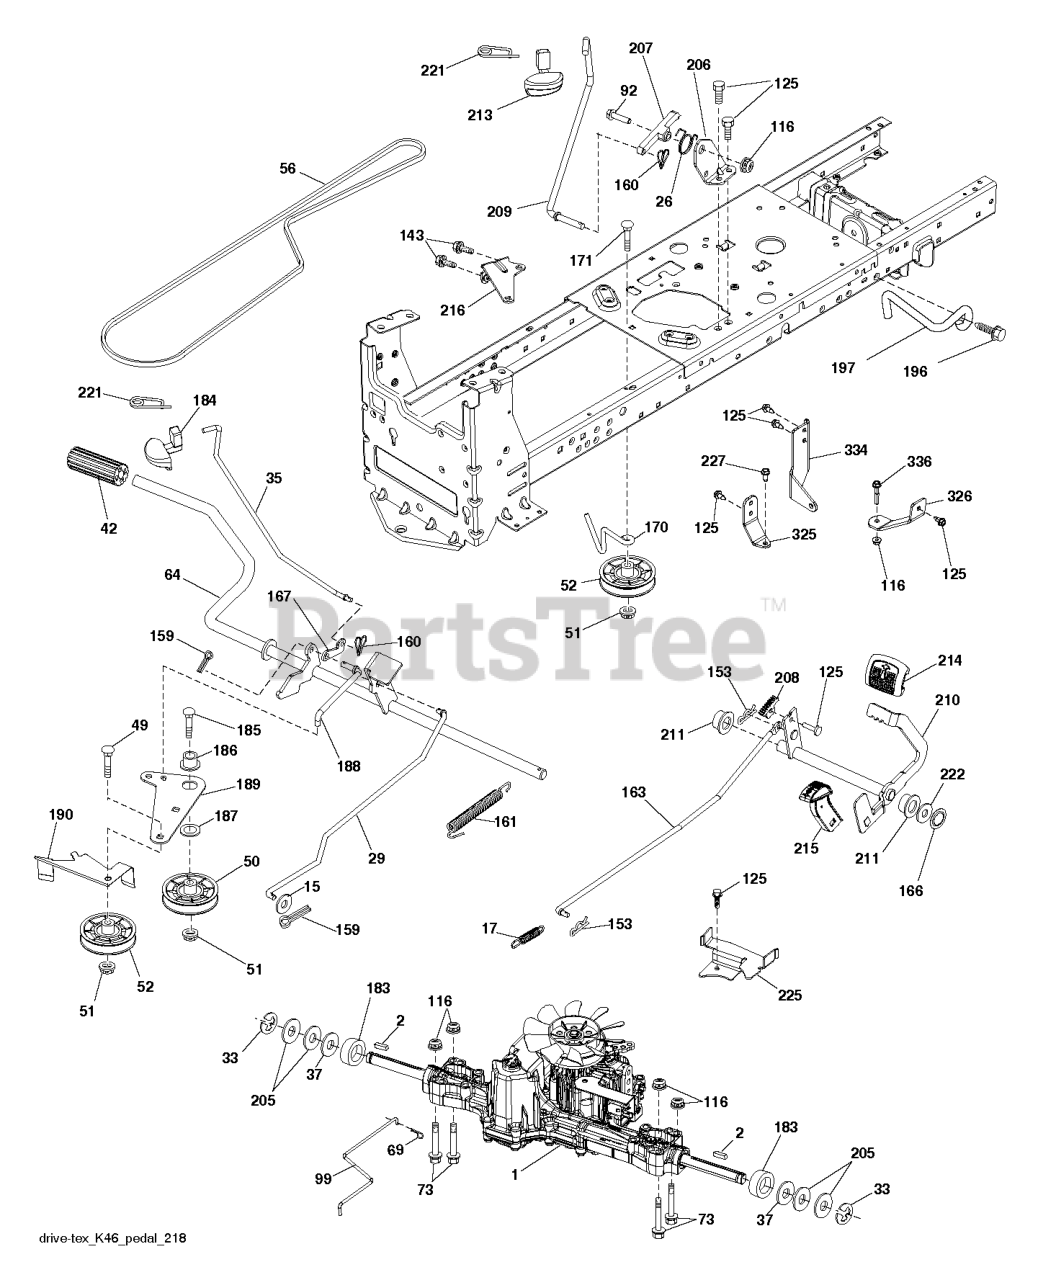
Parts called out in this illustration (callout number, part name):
2	SQUARE KEY
15	WASHER
17	SPRING.BRAKE.K46.GREEN
26	SPRING.RETURN.CRUISE
29	ROD.BRAKE.K46
35	ROD ROD.PARKINGBRAKE.GT.HUSQ/P
37	WASHER.HARDENED
42	PEDAL COVER T
50	IDLER.FLAT.910.OFFSET
51	NUT LOCK FLG 3/8-16 UNC
52	IDLER.V-GROOVE.910.OFFSET
56	V-BELT.MOWER.92.40.42/K46
64	SHAFT.ASM.PEDAL.BRK.CNTR
69	HAIRPIN.SOFT.ZINC.059X1.125
73	BOLT
92	BOLT
99	ARM.PIVOTING.TCRD.GEN2.5.BAGGE
116	NUT LOCK HEX FLANGE 5/16-18
125	SCREW
143	SCR 5/16-18 X 1/2 SELFTAP ZN
153	RETAINER M
159	COTTER PIN
160	RETAINER CLIP
161	SPRING, RETURN LT
163	ROD.CONTROL.K57R.K46
166	NUT.PUSH.625
167	LATCH.BRAKE.SPRING
170	KEEPER.V-IDLER.CENTER.
171	BOLT
183	SPACER AXLE
184	HANDLE.PARKING.BRAKE.H (BLK)
186	SPACER.RETAINER
187	WASHER 12/32X2X10GA
188	LINK.CLUTCH.GROUND DRIVE.LONG
189	BELLCRANK.GROUND.DRIVE.TEX.
190	KEEPER.BELLCRANK.DRIVE
196	SCREW 3/8-16X1
197	CLUTCH.ANTIROTATION.WIREFORM.
206	BRACKET.MOUNT.CRUISE.LATCH
207	LATCH.CONTROL.CRUISE.TEX
208	GEAR.SECTOR.CONTROL.CR
209	ROD ROD.CRUISECONTROL.GT.HUSQ/
210	ROCKER.ASM.PEDAL.CONTR
211	BEARING.NYLON
213	KNOB.CONTROL.CRUSIE.HU
214	PEDAL.FORWARD.PAD.TEX
215	PEDAL.COVER.REVERSE.CRD.X428BK
216	BRACKET.PULLEY.IDLER.W/TEX
221	RETAINER.SPRING.CLIP.H
222	WASHER 21/32 X 1-1/4 X 10 GA.
225	KEEPER.BELT.TRANSAXLE.K46
227	SCREW.THDROL.5/16-18X3/4.TTY
325	BRACKET.TRQ.STP.46.20".TIRE.LH
326	BRCKT.PNT.TRQ.STP.46.20TIRE.RH
334	SWAY.ROD.BRACKET.K46
336	BOLT.5/16-18X1-3/4.FLANGED.HEX
